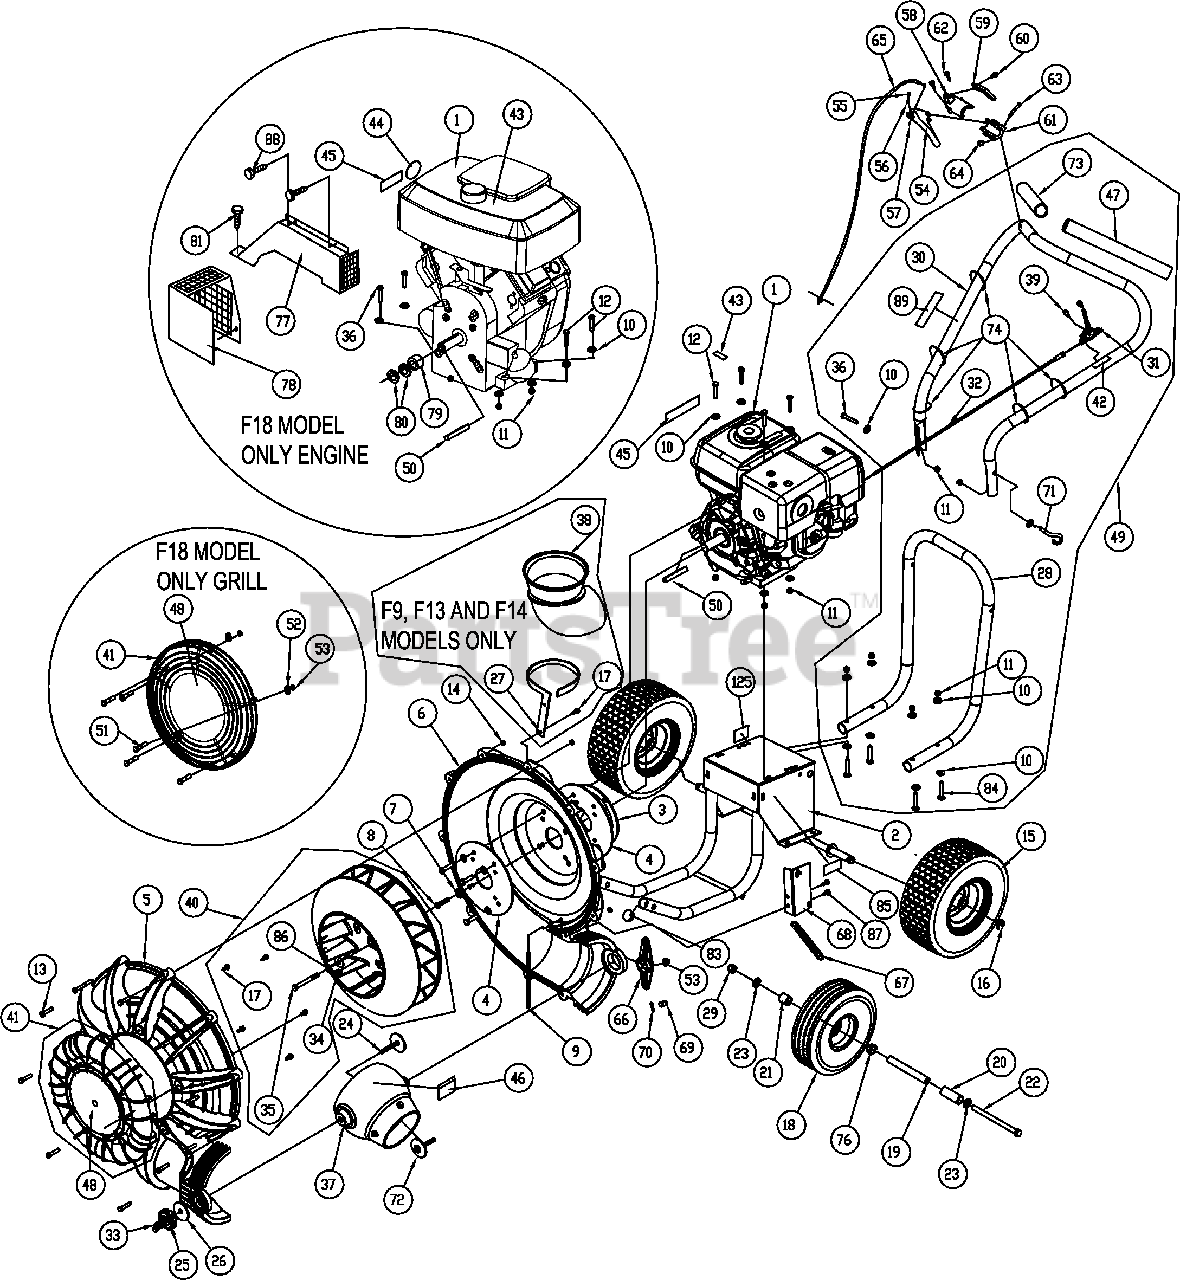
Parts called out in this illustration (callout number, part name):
1	ENGINE 18 VANGUARD
2	BASE ENGINE WA FSP
3	SPACER RING ENGINE
4	PLATE REINFORCE HOUSING
5	HOUSING FRONT MOLDED
6	HOUSING BACK MOLDED
7	WASHER LOCK
8	SCREW CAP 3/8-16X 2" ZP
9	ROD HAND STOP
10	WASHER 5/16 FLATWASHER Z/P
11	NYLON INSERT LOCKNUT 5/16-18
12	SCREWCAP 5/16-18 X 1.75 ZP
13	SCREWCAP 1/4-20 x 1 1/2
14	NUT FLANGE 1/4-20
15	WHEEL & TIRE 13" X 5" PNEUMATIC
16	RING RETAINING 3/4
17	SCREW SELF-TAP 5/16 NC X 3/4 HEX
18	WHEEL ASSY 10 " PNEUMATIC
19	SPACER FRONT AXLE
20	SPACER LH WHEEL FRONT
21	SPACER RH WHEEL FRONT
22	SCREWCAP 1/2-13 x 9 1/2"
23	WASHER FLAT 1/2" SAE
24	WASHER W/BOLT WA
25	KNOB 3/8-16 SOLID HUB
26	WASHER 2.25 OD x .515 ID x .134 ZP
27	BRACKET HOLDER WA
28	HANDLE LOWER
29	NYLON INSERT LOCKNUT 1/2-13
30	HANDLE UPPER
31	CONTROL THROTTLE
32	CABLE THROTTLE CONTROL
33	NUT LOCK 3/8-16 LT WT THIN ZP
34	WASHER 1.5 O.D.X 0.45 I.D. X 0.5
35	SCREWCAP 3/8-24 X 4 GR.8 (38 +/-2 ft-lbs)
36	SCREWCAP 5/16"-18 X 2" ZP
37	DIRECTOR CONE 6"
38	DIVERTOR FRONT
39	SCREW SM #10-24X1/2" DRILL POINT
40	IMPELLER SERVICE ASSY FORCE 18HP
41	GRILL FRONT BLOWER
42	LABEL THROTTLE CONTROL
43	LABEL FUEL EN/SP
45	LABEL SAFETY PROTECT READ MANUAL
46	LABEL DANGER FLYING DEBRIS
47	GRIP 1-1/4" ID x 13"
48	LABEL FORCE
49	HANDLE ASSY UPPER
50	KEY 1/4" SQ x 2.75
51	SCREWCAP 1/4-20 X 1"
52	WASHER FLAT 1/4
53	NUT LOCK 1/4"-20 HEX ZP
54	HANDLE DIVERTER FORCE
55	PIN LATCH DIVERTER
56	SPRING COMPRESSION 0.281 X 0.88
57	RING RETAINING .122 DIA
58	SADDLE LOWER DIVERTER
59	PLATE LOCK DIVERTER
60	SCREW PLASTITE #6-19 X 5/8"
61	SADDLE UPPER DIVERTER
62	SCREW PLASTITE #10-14 X 1"
63	PIN PIVOT DIVERTER CONTROL
64	RING RETAINING 5/16
65	CABLE ASSY
66	DIVERTER PIVOT ADAPTOR
67	SPRING EXTENSION 0.468 X 5.25
68	BRACKET DIVERTER FORCE
69	PIN CLEVIS 1/4 X 3/4
70	.051 X 3/4" HITCH PIN CLIP
71	EYEBOLT PIGTAIL 5/16"-18 X 1 1/4"
72	ADAPTOR MOUNT WA
73	GRIP 1-1/4" ID x 9.5" LONG
76	FORCE WHEEL BEARING .751 ID
77	GUARD MANIFOLD
78	GUARD MUFFLER
79	SPACER 1" ID X 2" OD X 0.890 TK
80	SPACER 1" ID X 2" OD X 0.265 TK
81	SCREW SELF TAP 1/4"-20 X 5/8"
84	CARRIAGE BOLT 3/8"-16 X 2" ZP
85	SPARK ARRESTOR LABEL
86	WASHER LOCK 3/8 ST MED
87	SCREW PLASTITE 1/4"-10 X 3/4" HWH ZP
88	BOLT 1/4"-20 X 1/2" SER FLANGE
89	LABEL AIM AND SHOOT
125	LABEL MADE IN U.S.A.
